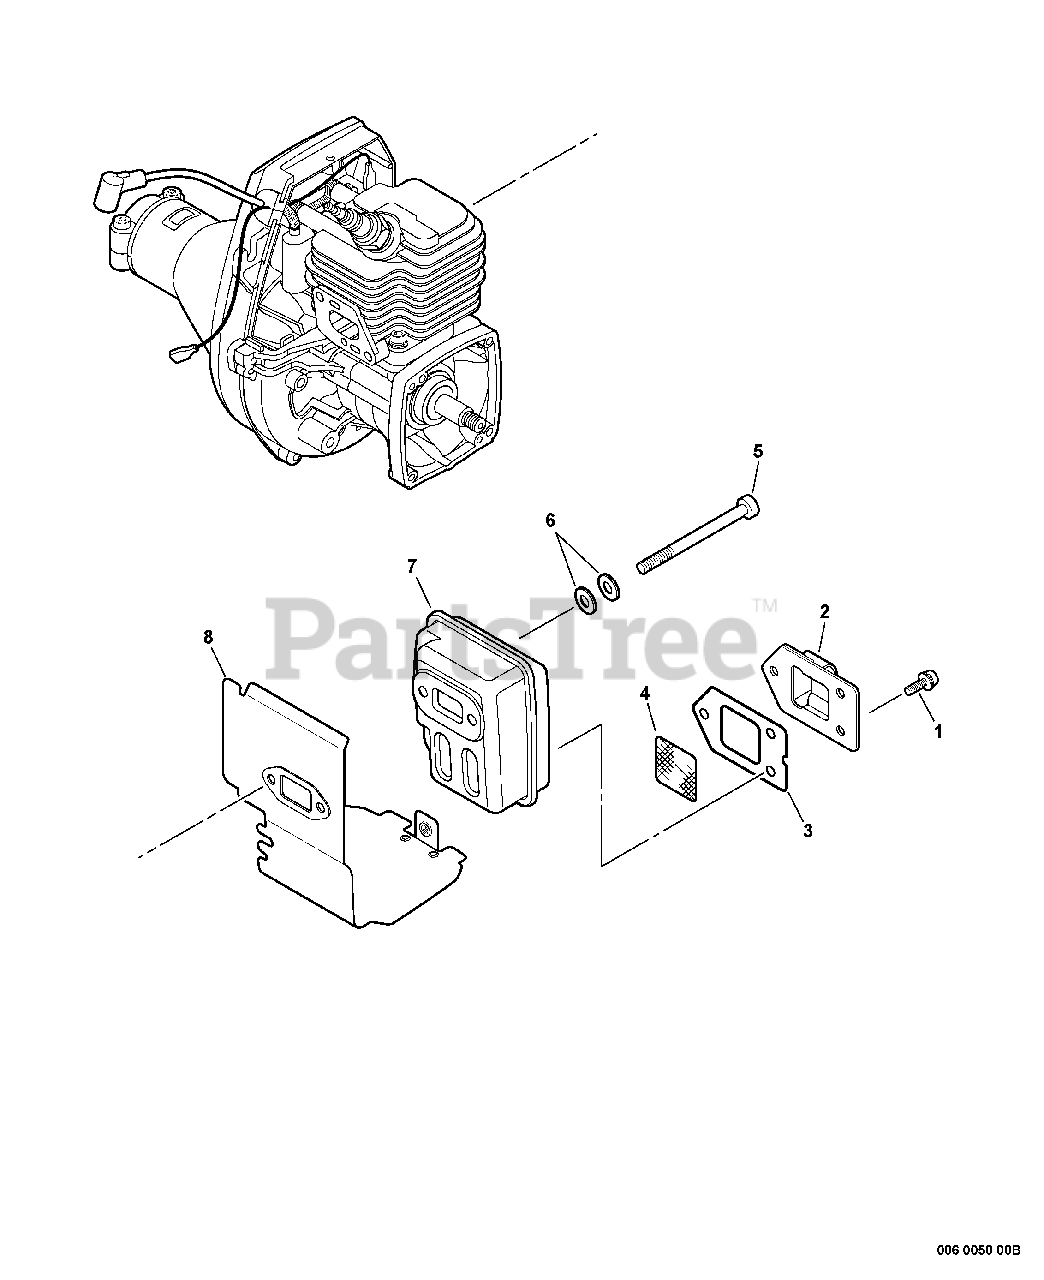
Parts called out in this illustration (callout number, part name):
1	SCREW 4×10
2	GUIDE, EXHAUST
3	GASKET, EXHAUST
4	SCREEN, SPARK ARRESTER
5	BOLT 5×55
6	WASHER, FLAT 5.5×10×0.8
8	HEAT SHIELD, EXHAUST
